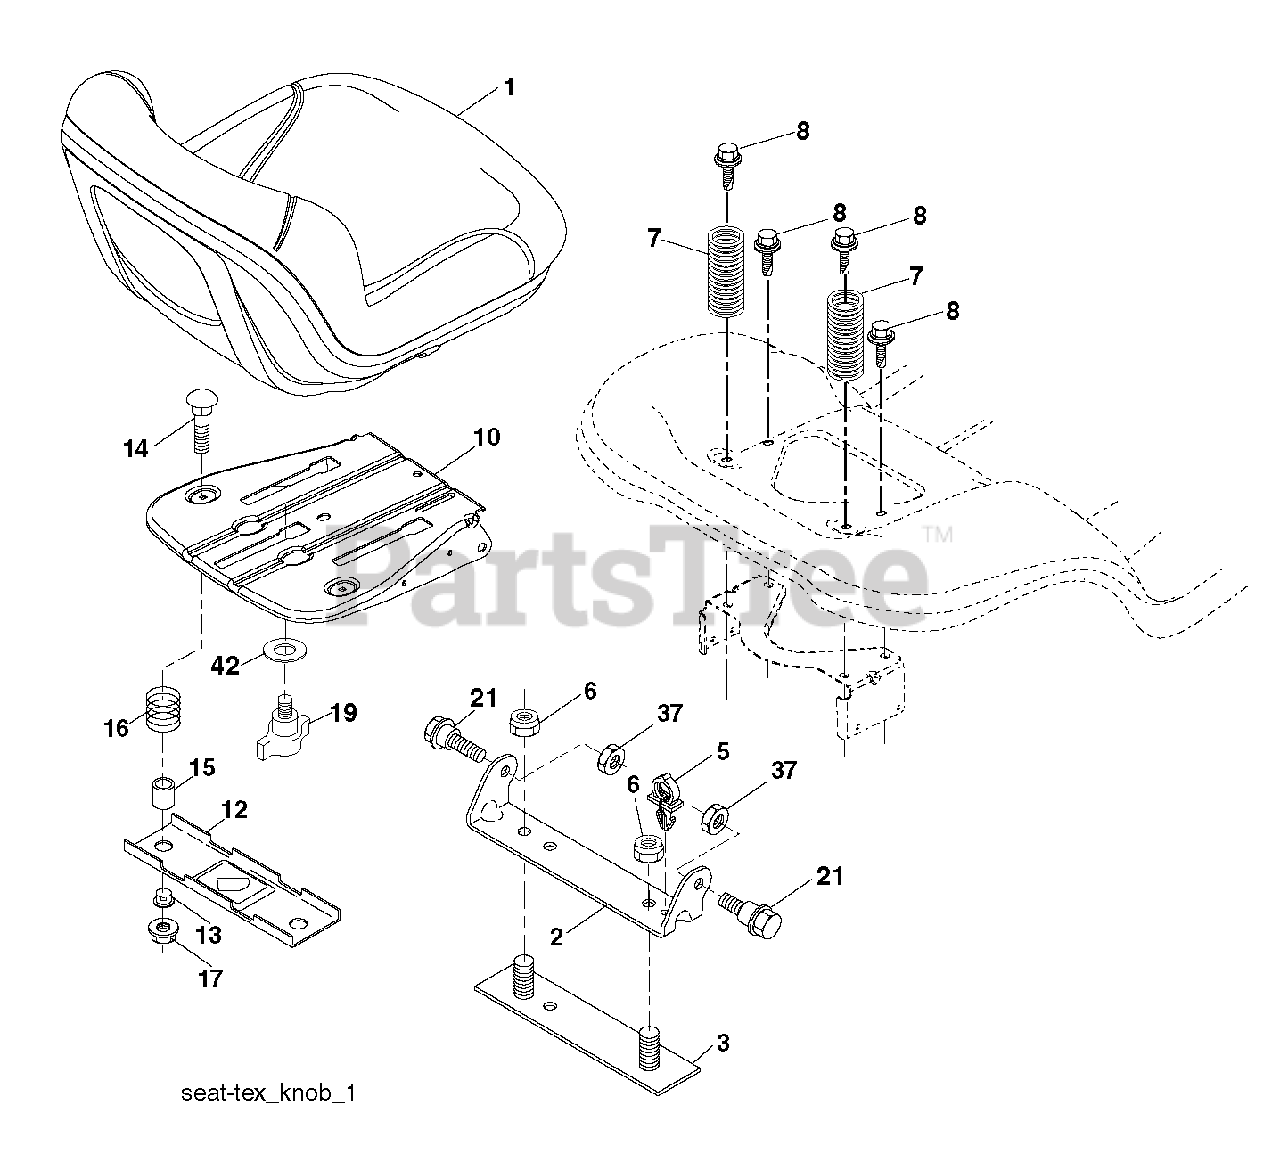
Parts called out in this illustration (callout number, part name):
1	SEAT.TP130.BLK.PPRO.MILSCO
2	BRKT.PIVOT.FENDER
5	PUSH CLIP
6	NUT
7	Compression Spring, Seat Black
8	BOLT, 5/16-18 X 1 3/4
10	PAN.ASM.SEAT.SHORT.SLD.ADJ.TEX
12	BRKT.MNT.OPC.SW.SEAT.
14	BOLT.ROUND.HEAD.SQUARE.NECK
15	SPACER SPLIT 28X.96
16	SPRING COMPRESSED
17	NUT T
19	KNOB.SEAT.ADJ.
21	Shoulder Bolt, 5/16-18 X 5/8
37	NUT.71038.31-18.HEX.NYLOCK
42	WASHER.CUP.SEAT.
